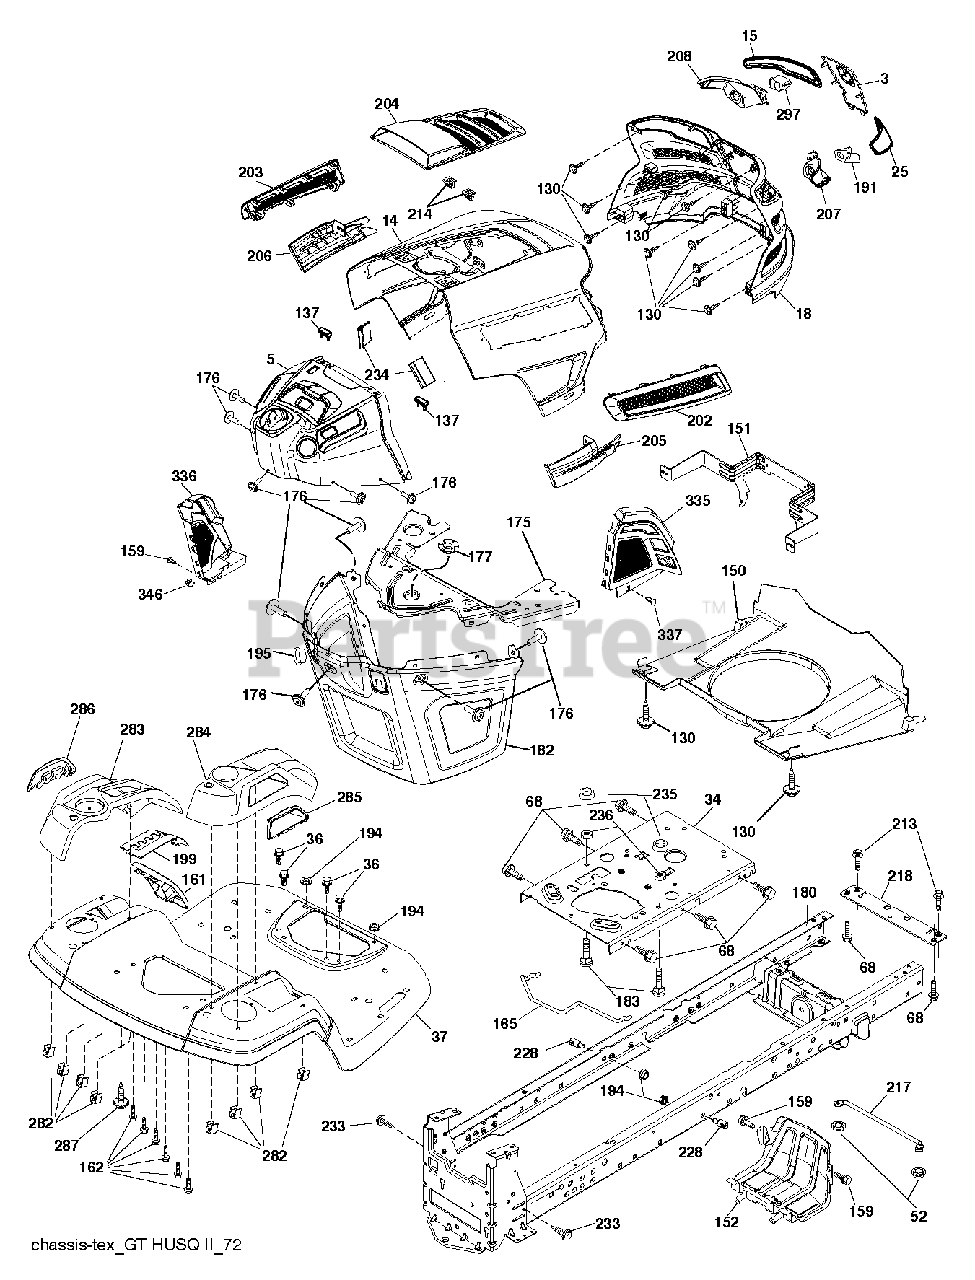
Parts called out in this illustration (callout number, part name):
3	APPLIQUE.SUBASM.GT.HUSQ.II
5	DASH.UPR.ASSY.GT2.SRVMNDER.PTO
14	HOOD.ASM.HUSQVARNA.GT.TEX.ORAN
15	LENS.HEADLIGHT.LH.GTII.2011
18	GRILLE.SUBASM.GT.HUSQ.II
25	LENS.HEADLIGHT.RH.GTII.2011
34	PLATE.ENGINE.WELDED.CHASSIS
36	SCREW 5/16"
37	FENDER.TLT.FS.W/CPH/FW/RSF.668
52	LOCKNUT
68	SCREW LT
130	SCREW.#10 X 0.750.BOS
137	BUMPER DASH
150	AIR.DUCT.GTV.BLACK
151	BRACKET.PIVOT.HOOD.GT.HUSQ.II
152	SHIELD.BROWNING.PNT.GT.V2
159	SCREW, 3/8-16X3/4
161	WINDOW.FUEL.LT.HUSQ.TEX.498
162	SCREW.HI-LO.CONSOLE
165	SUPPORT.TANK.REAR.W/TEX
175	PLATE.CROSSMEMBER.HUSQ
176	SCREW.#10-24X5/8.RN.QU
177	BUSHING, STEERING
180	CHASSIS
182	DASH.LOWER.COMMON.12V.ADAPTOR
183	BOLT.5/16-18X1-1/4 FULL.THREAD
191	INSERT.REFLECTIVE.RH.HUSQ.GTII
194	NUT LOCK HEX FLANGE 5/16-18
195	PLUG.HOLE.DASH.LOWER.12V.BLK
199	PLATE.DECK.LIFT.HUSQ.LT
202	VENT.SIDE.RH.GT.HUSQ.II.
203	VENT.SIDE.LH.GT.HUSQ.II.498
204	VENT.TOP.HUSQ.GT2
205	SIDE.TRIM.RH.GT.HUSQ.II
206	SIDE.TRIM.LH.GT.HUSQ.II.GRAY
207	BEZEL LIGHT.RH.GT.II.MYLAR
208	BEZEL LIGHT.LH.GT.II.MYLAR
213	BOLT
214	CLIP.RETAINER.TINNER.
217	ROD.PIVOT.HOOD
218	X-PIECE.HOOD.STOP.NON/
228	STUD.FASTNER.W/ANTI-ROTATE
233	BOLT.SHOULDER
234	BUMPER.HOOD.TEX.HUSQVARNA
235	SPACER FENDER
236	NUT.CENTERLOCK.5/16-
282	CLIP.RETAINER.CONSOLE.LT.HUSQ
283	CONSOLE.DECK.LIFT.R.SDFL.HUSQ
284	CONCOLE.CNTRL.PDL.HUSQ.LT.498
285	CONSOLE INSERT RH
286	CONSOLE.INSRT.LH.HUSQ.LT.BLACK
287	SCREW 1/4X20
297	INSERT.REFLECTIVE.LH.HUSQ.GTII
335	COVER.RH.CLOSE.OUT.BLACK
336	COVER-LH.LOWER.DASH.GT2.BLACK
337	CLIP.XMAS.TREE.ITW.2622-00
346	CLIP,INSULATOR
